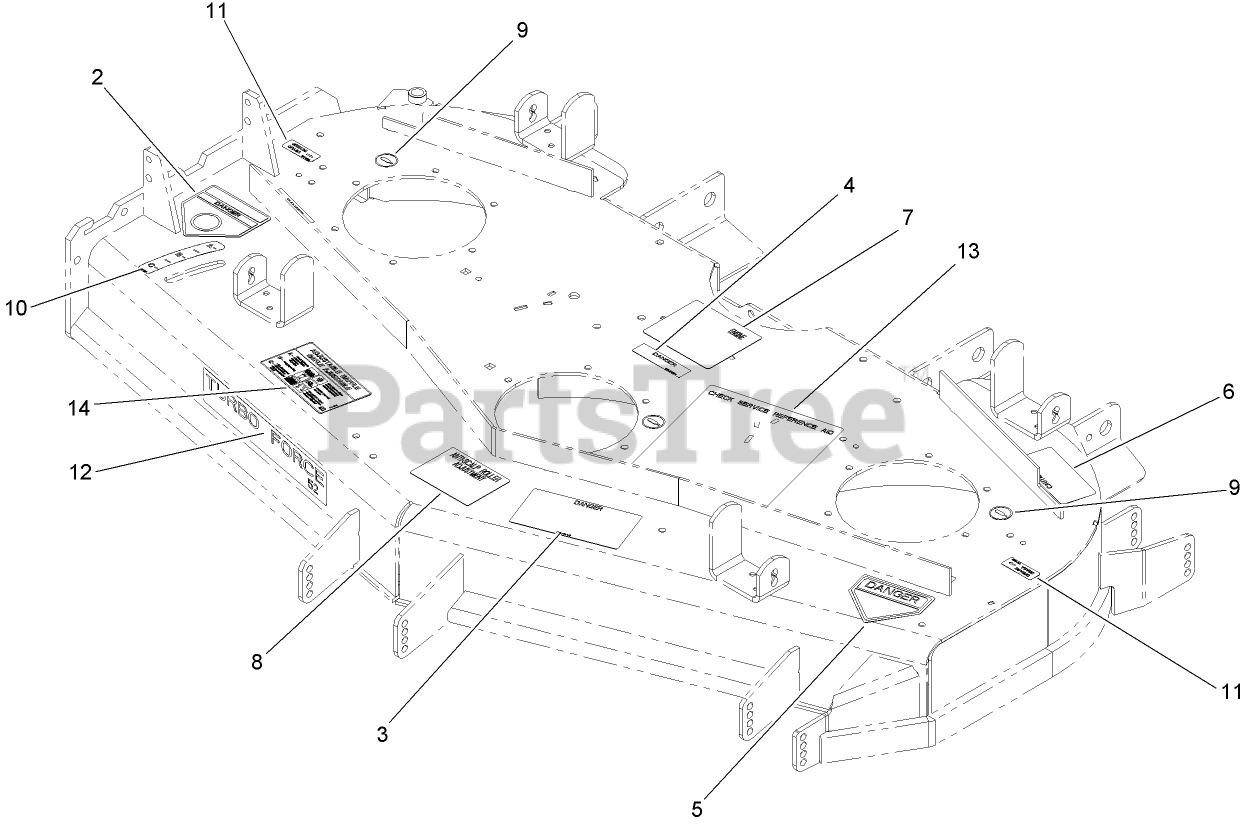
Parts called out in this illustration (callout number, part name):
2	DECAL-DANGER
3	DECAL-DANGER, THROWN OBJECT
4	DECAL-COVER, MISSING
5	DECAL-DANGER
6	DECAL-TORQUE
7	Decal-Routing, Belt
8	DECAL-SCALP, ANTI
9	DECAL-GREASE
10	DECAL-SETTING, BAFFLE
11	Decal-Grease
13	Decal-Service, Check
14	DECAL-ADJUSTMENT, BAFFLE
